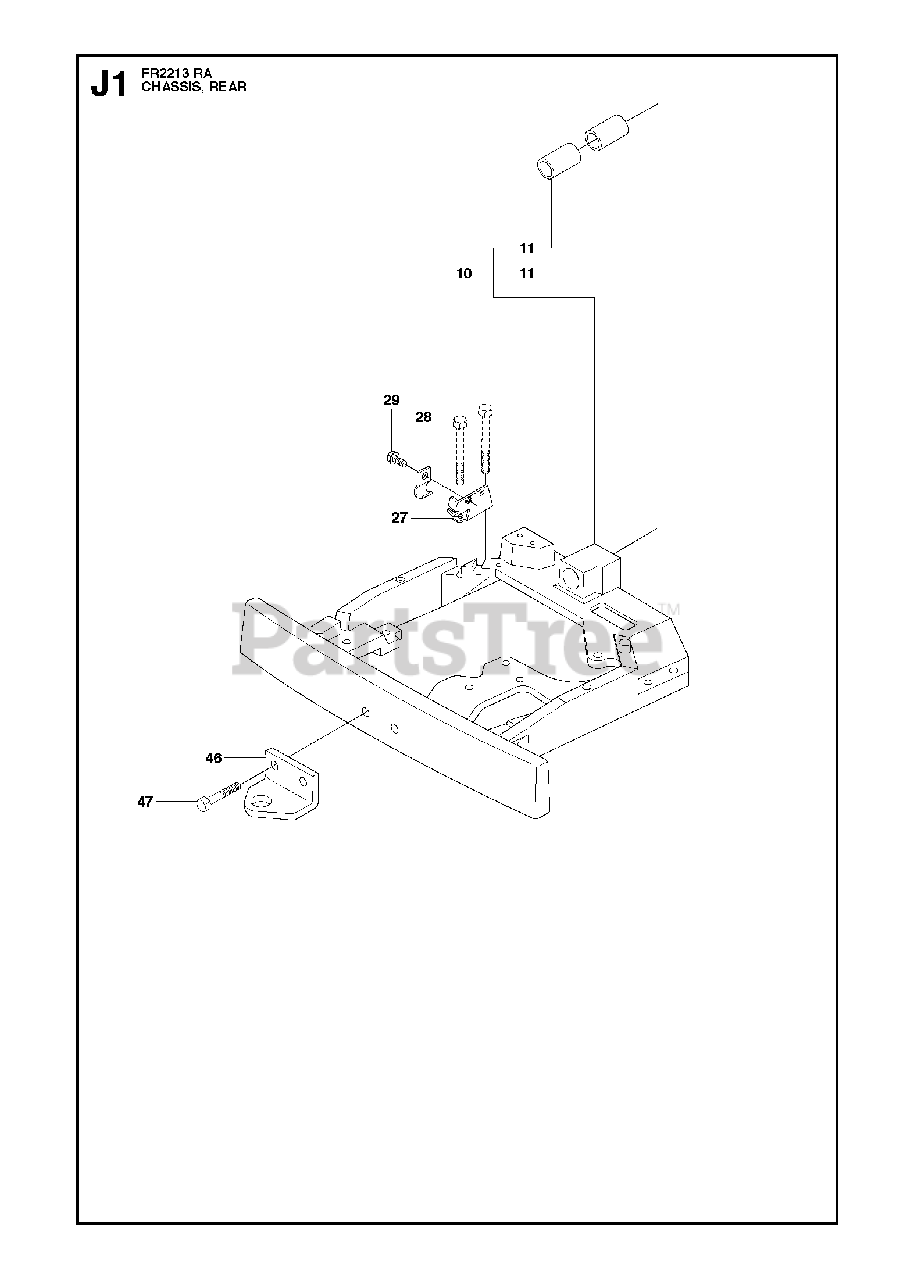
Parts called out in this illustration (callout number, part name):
11	BUSHING
46	DRAW RING
47	SCREW M10X25
